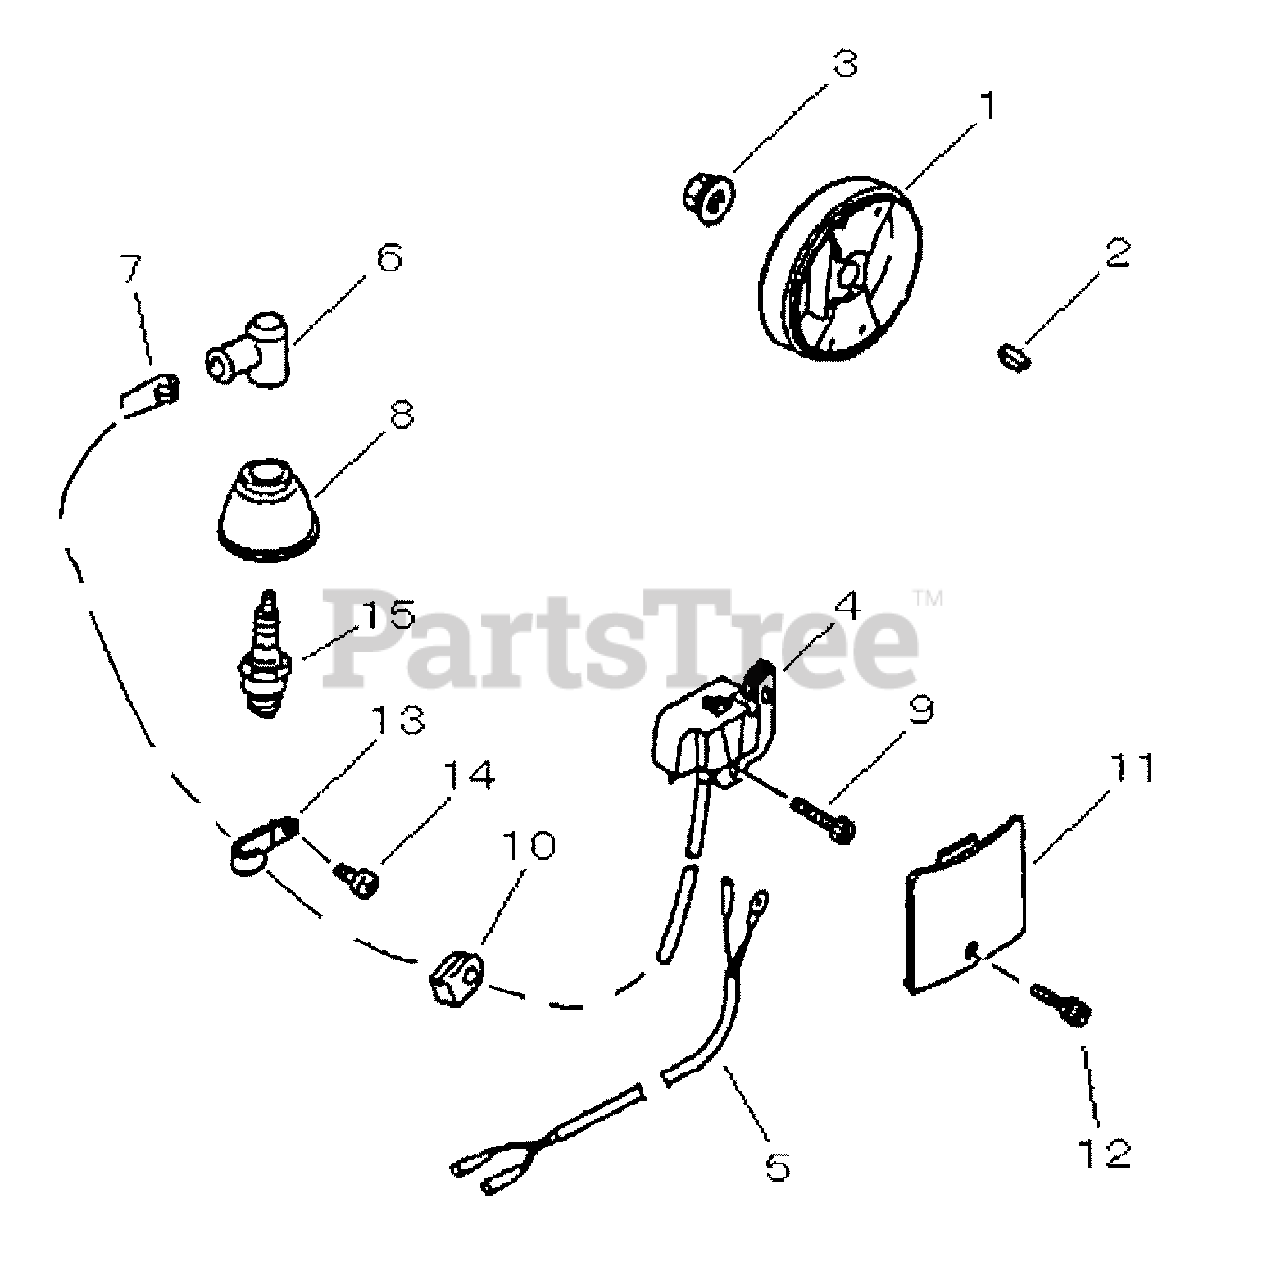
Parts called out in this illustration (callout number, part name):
1	FLYWHEEL
2	KEY
3	NUT - 10 -- FLANGE
4	COIL, IGNITION
5	LEAD ASSY
6	CAP, SPARK PLUG
7	TERMINAL, SPARK PLUG CAP
8	COVER, SPARK PLUG CAP
9	SCREW - 4X20
10	GROMMET
12	BOLT - 4X16
13	CLAMP
14	SCREW - 5X14 -- TAPPING
15	SPARK PLUG -- RCJ-6Y
